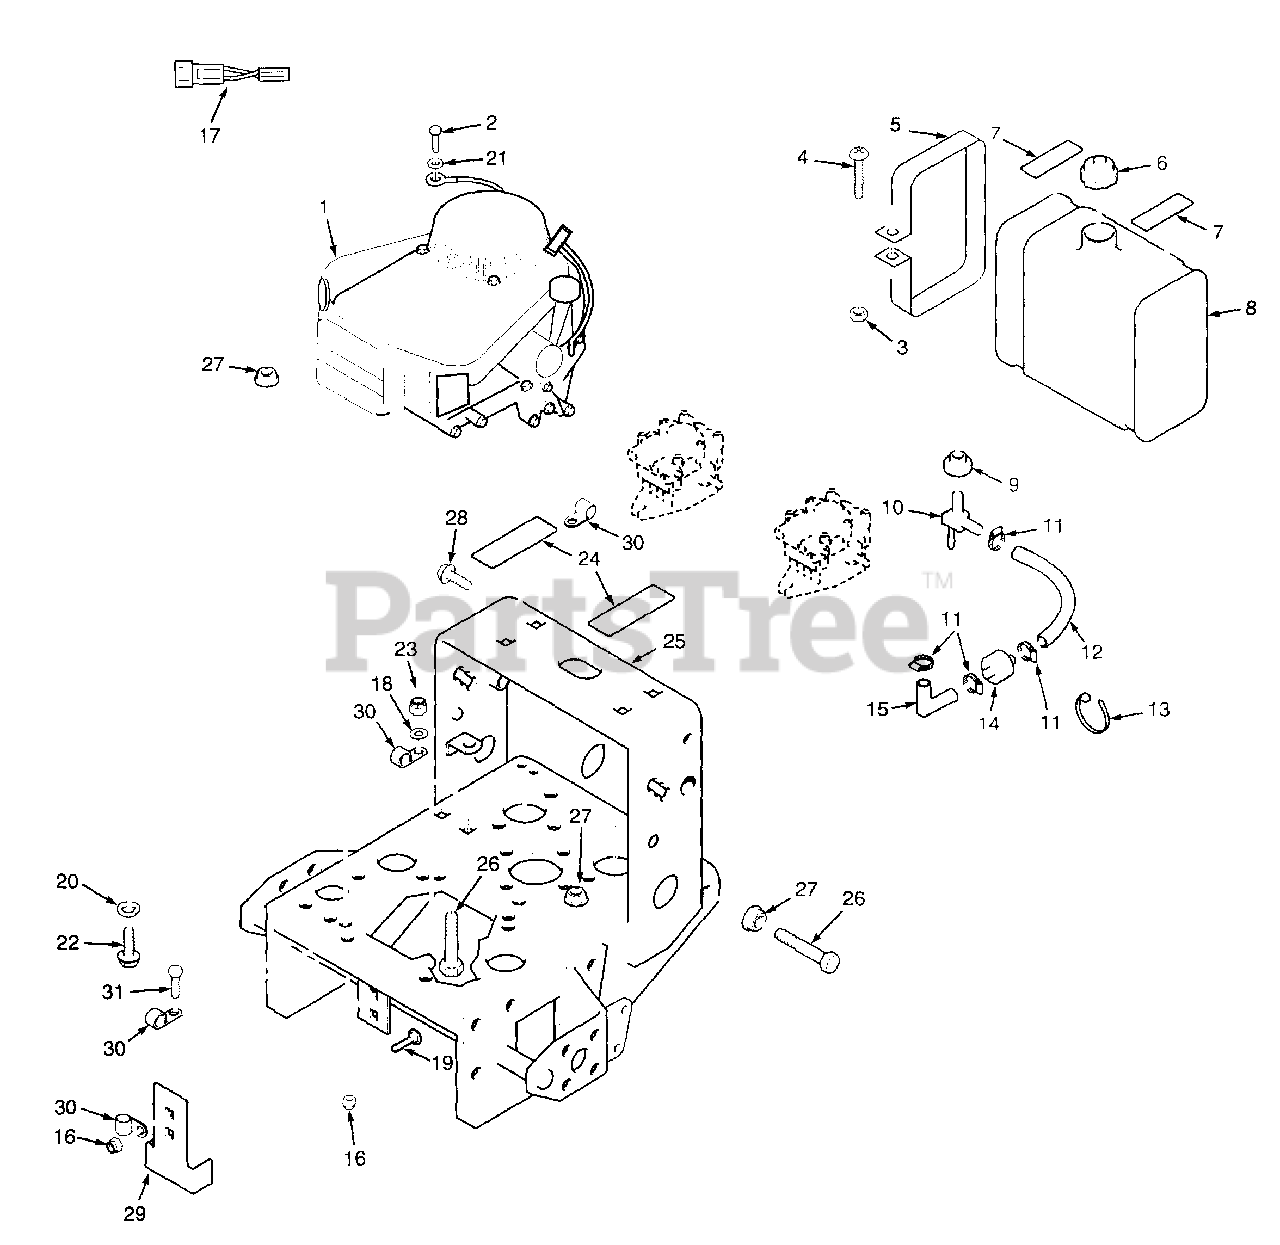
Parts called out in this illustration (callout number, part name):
1	Engine, 17KA Kawasaki
2	Bolt, Hex Head M8-1.25 x 10mm
3	Hex Nut, 1/4-20
4	Screw, 1/4-20 x 2" Rnd. Hd Phillips
5	Strap, Fuel Tank
6	Cap, Fuel Tank
7	Pad, Rubber-Fuel Tank Upper
8	Fuel Tank Assembly
9	Bushing
10	Valve, Fuel Shut-Off
11	Clamp, Fuel Hose
12	Fuel Hose, 1/4 I.D. x 20"
13	Cable Tie
14	Fuel Filter
15	Fuel Hose, 7/32 I.D. x 3.5"
16	Nut, Hex Elastic Stop 5/16-18
17	Wire Harness Adapter
18	Flat Washer, 14"
19	Bolt, Carriage 5/16-18 x 1"
20	Lock Washer, 5/16"
21	Lock Washer, 5/16" Int. Tooth
22	Capscrew, Hex Serrated Flange 5/16-18 x 1.5"
23	Nut, Hex Elastic Stop 1/4-20
24	Pad, Rubber-Fuel Tank Lower
25	Engine Deck, 16" Wide W/Decals
26	Bolt, Hex Head 1/4-20 x 1.25"
27	Nut, Hex Serrated Flange 1/4-20
28	Capscrew, Hex Serrated Flange 5/16-18 x 1.25"
30	Clutch Bracket
31	Bolt, Hex Head 5/16-18 x .75"
